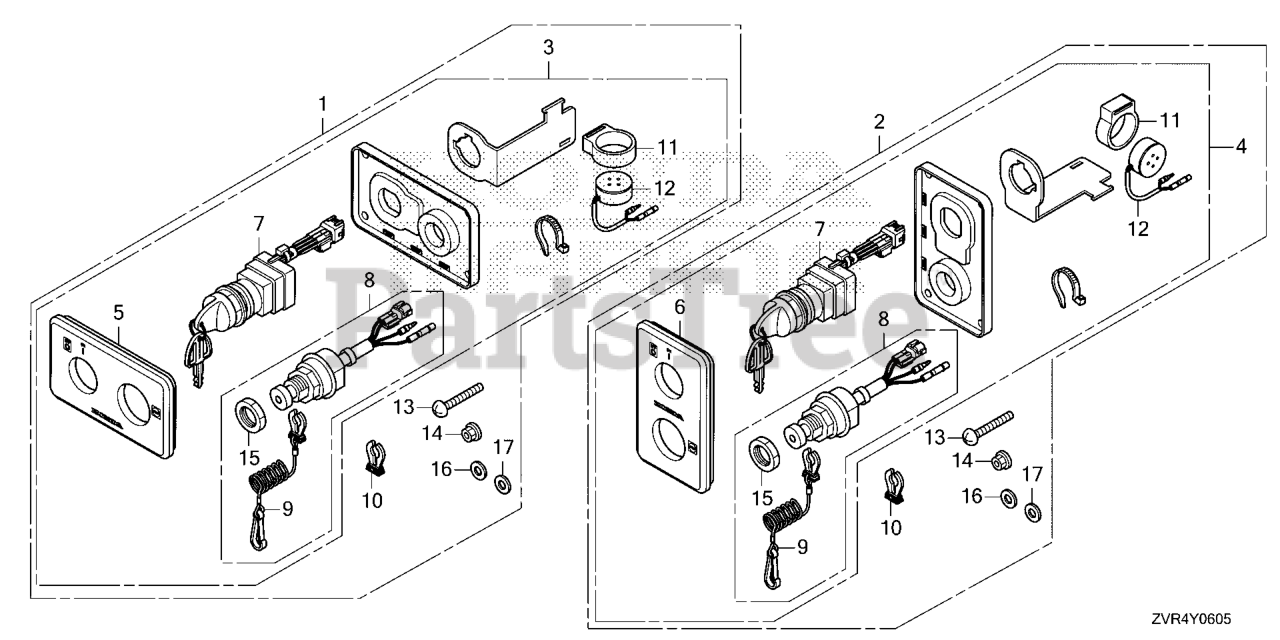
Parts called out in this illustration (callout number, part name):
1	PANEL KIT, KEY SW
2	PANEL KIT, KEY SW
3	PANEL ASSY., KEY SW
4	PANEL ASSY., KEY SW
5	PANEL, KEY SWITCH (START)
5	PANEL, KEY SWITCH
6	PANEL, KEY SWITCH
6	PANEL, KEY SWITCH (START)
7	SW ASSY., COMB
8	SWITCH ASSY., EMERGENCY STOP
9	WIRE, EMERGENCY
10	CLIP, EMERGENCY LOCK
11	SUSPENSION, AUDIBLE PILOT
12	BUZZER, WARNING
13	SCREW, PAN (5X40) DUAL QTY = (8) (SINGLE)
14	NUT, FLANGE (5MM)
15	NUT
16	WASHER, PLAIN (5MM)
17	WASHER, SPG (5MM)
